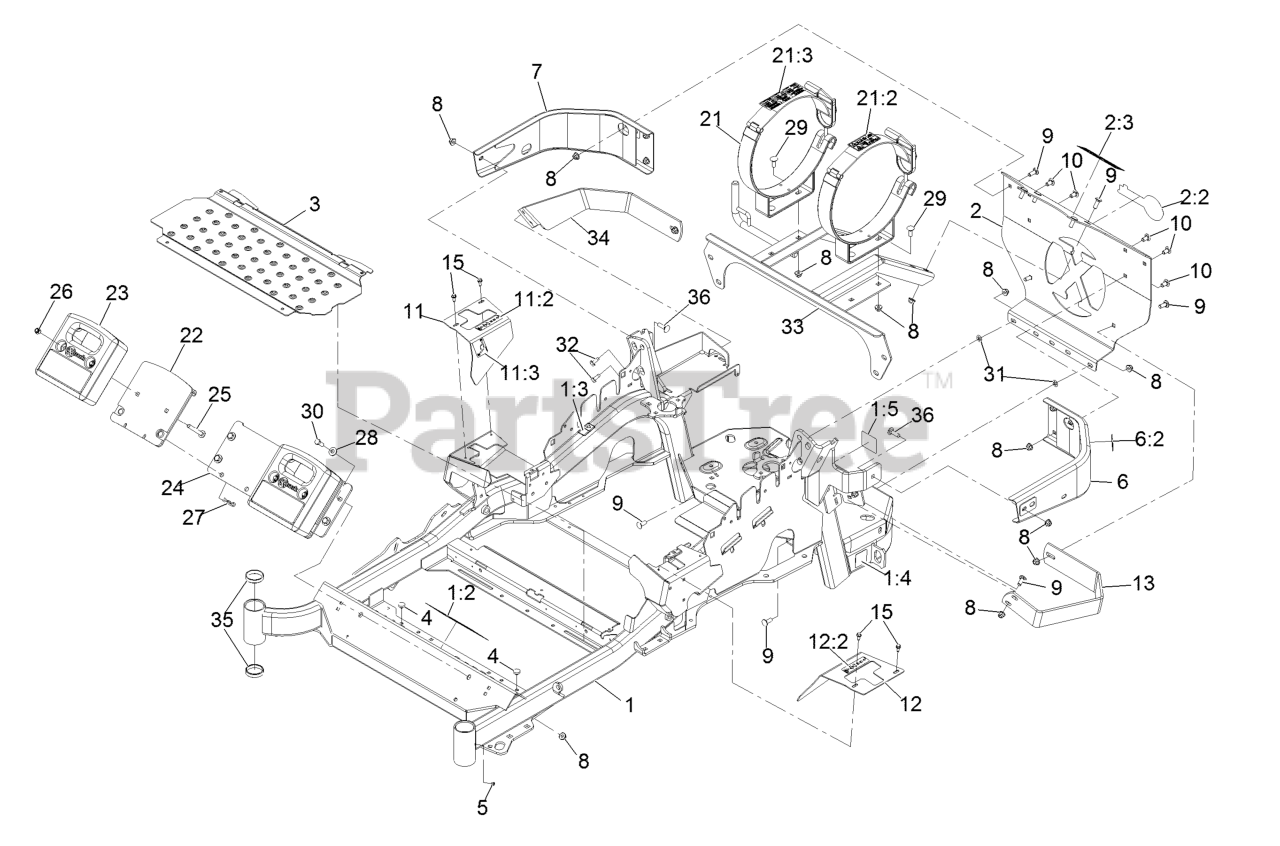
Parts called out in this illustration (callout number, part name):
1	Mainframe ASM
1:2	Decal-Danger
1:3	Decal-Warning
1:4	Decal-Hazard, Pinched Finger
1:5	Decal-Spark Arrester
2	Rear Guard-LP W/Decals
2:2	Decal-Exmark Logo
2:3	Decal-LPG Fuel Tank Replacement
6	LH Bumper ASM
6:2	Decal-Warning
7	Bumper-RH
8	Nut-HF, NI
9	Screw-CARR
10	Screw-CARR
11	RH Motion Control Cover ASM
11:2	Decal-Control, Motion
11:3	Decal-Park Brake, CE
12	LH Motion Control Cover ASM
12:2	Decal-Control, Motion
13	Guard-Muffler
15	Screw-HWH
21	Tank Bracket ASM (Set)
21:2	Decal-LPG Warning
21:3	Decal-LPG Tank Spec
22	Asm, Weight W/Decals
23	Weight,Cast 36Lb
24	Plate, Weight Mounting
25	Screw-CARR
26	Nut-Lock, NI
27	Pin-Hair
28	Washer-Belleville
29	Bolt-CARR
30	Screw-HH
31	Nut-Push
32	Screw-HWHTF
33	Support-LPG Tank
34	Strap-Guard
35	Cup-Bearing
36	Bolt-CARR
